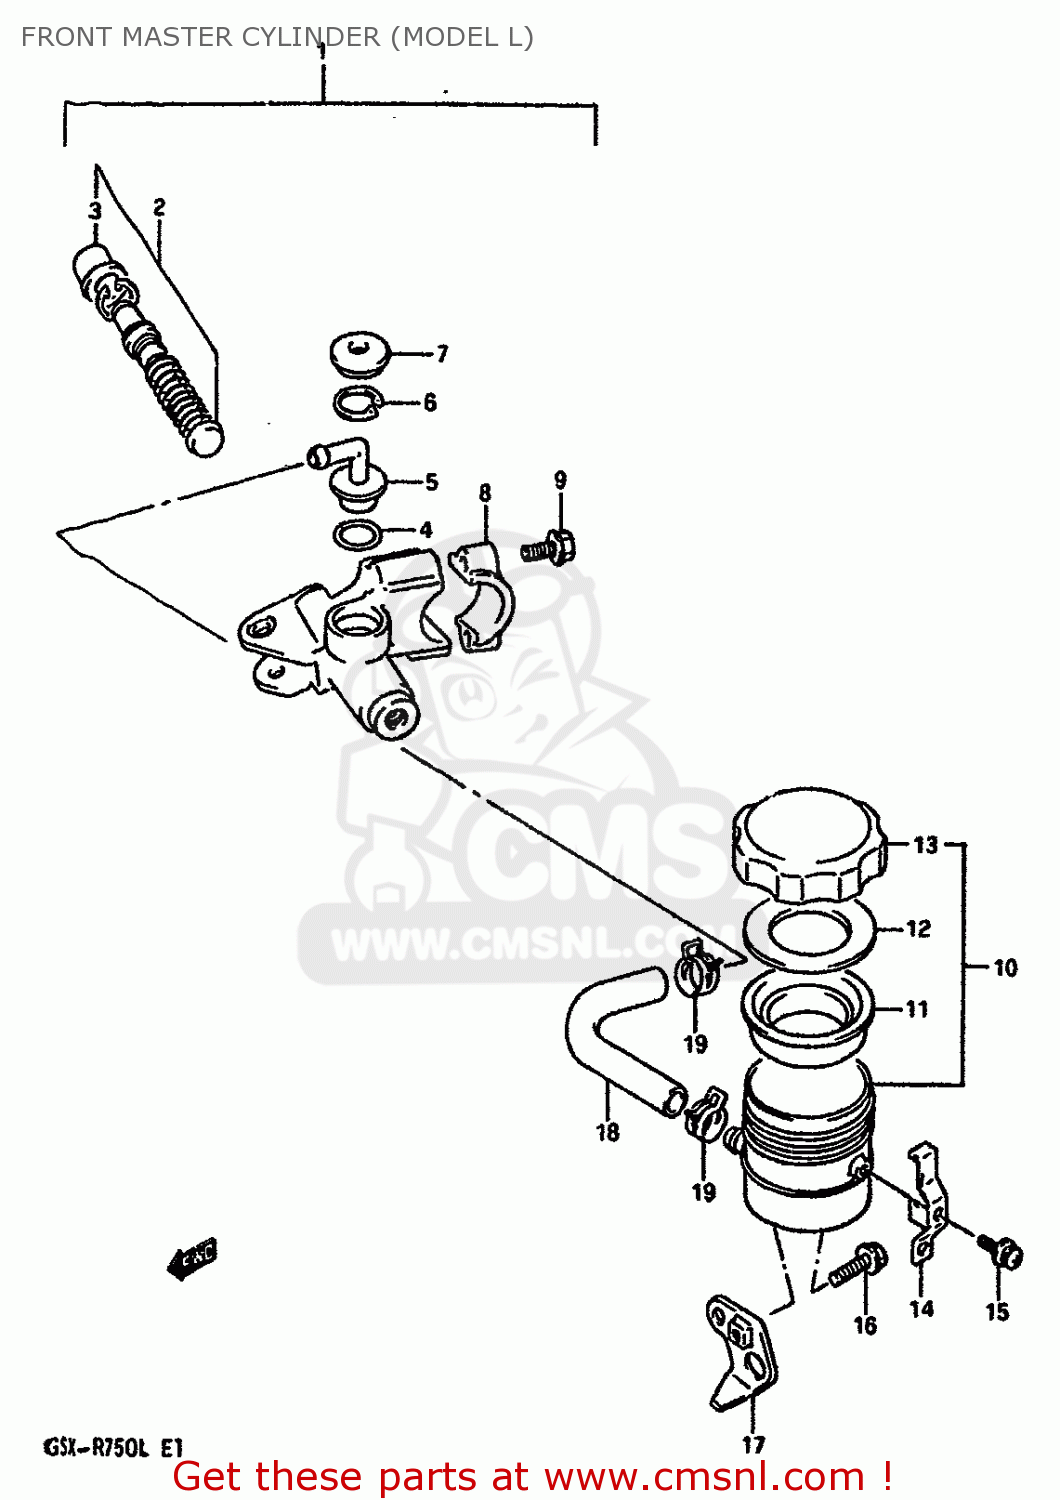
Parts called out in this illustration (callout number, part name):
1	CYLINDER ASSEMBLY,FRONT MASTER
2	PISTON & CUP SET
3	BOOT
4	O RING
5	CONNECTOR
6	CIRCLIP
7	COVER,DUST
8	HOLDER
9	BOLT
10	TANK ASSY,RESERVOIR
11	DIAPHRAGM
12	PLATE,DIAPHRAGM
13	CAP
14	PLATE,RESERVOIR TANK CAP
15	SCREW
16	BOLT 6X16
17	BRACKET COMP,RESERVOIR
18	HOSE,RESERVOIR TANK FR
19	CLAMP,RESERVOIR TANK FR
20	HOSE,RESERVOIR TANK FR
21	CLAMP,RESERVOIR TANK FR
